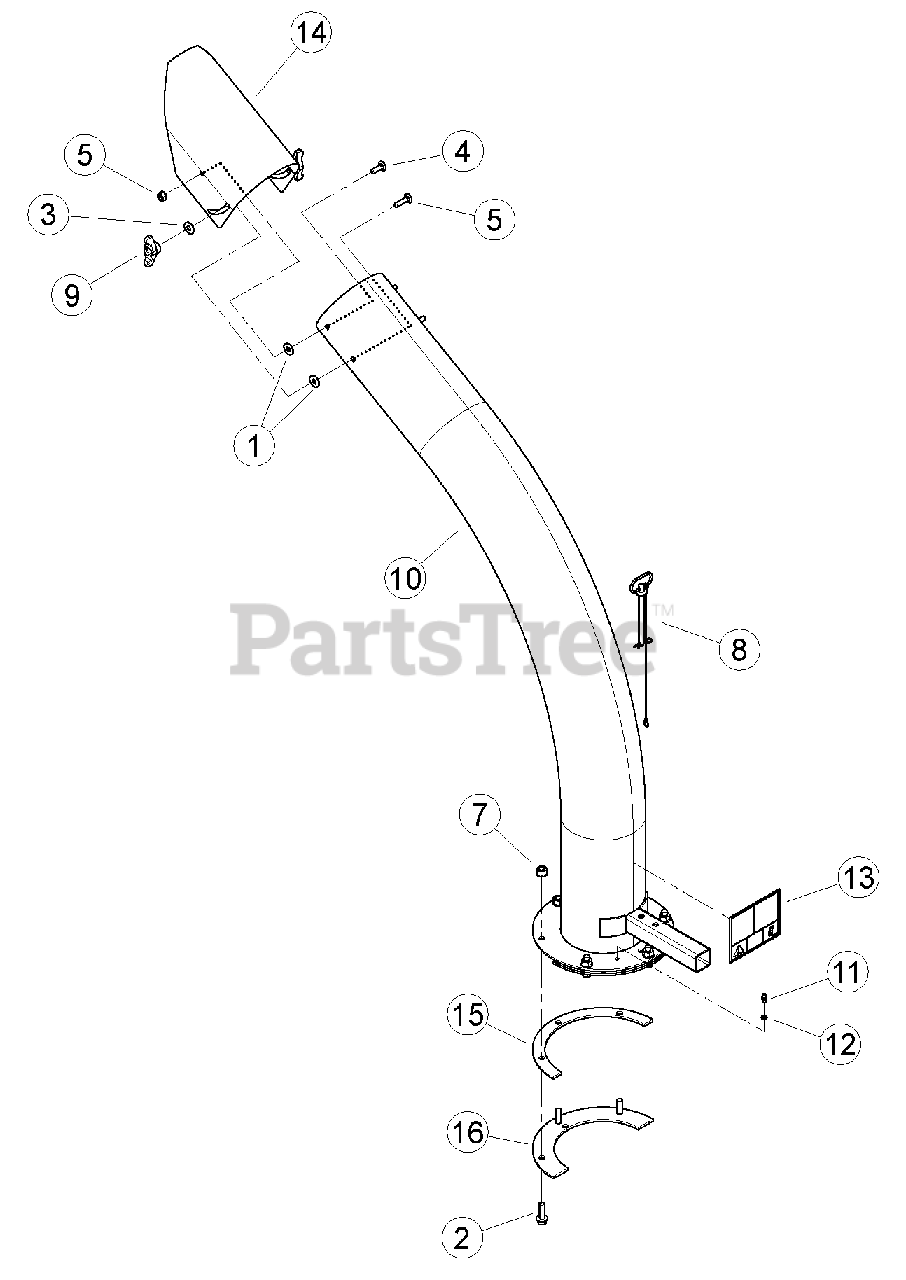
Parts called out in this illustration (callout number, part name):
1	WASHER, 3/8 FLAT
2	BOLT, 3/8 X 1-1/4 FLANGE NC
3	WASHER, 5/16 FLAT
4	BOLT, 5/16-18 X 1 GR5 CRG
5	BOLT, 5/16 X 1-1/4 GR5 CRG
6	NUT, 5/16-18 NYLOCK FLANGE
7	NUT, 3/8-16 NYLOCK FLANGE
8	PIN, 3/8" X 4.25" DISCHARGE
9	KNOB, 5/16-18 UNC TEE W/ LOCKING INSERT
10	ASSEMBLY, 6 INCH DISCHARGE CHUTE
11	FITTING, 1/4 SELF-TAP GREASE
12	WASHER, FLAT .254 X .400 X .048
13	DECAL, DISCHARGE DEBRIS & LOCK
14	DEFLECTOR, BLOWER VAC DISCHARGE
15	SPACER, DISCHARGE PIVOT
16	RING, DISCHARGE CLAMP
